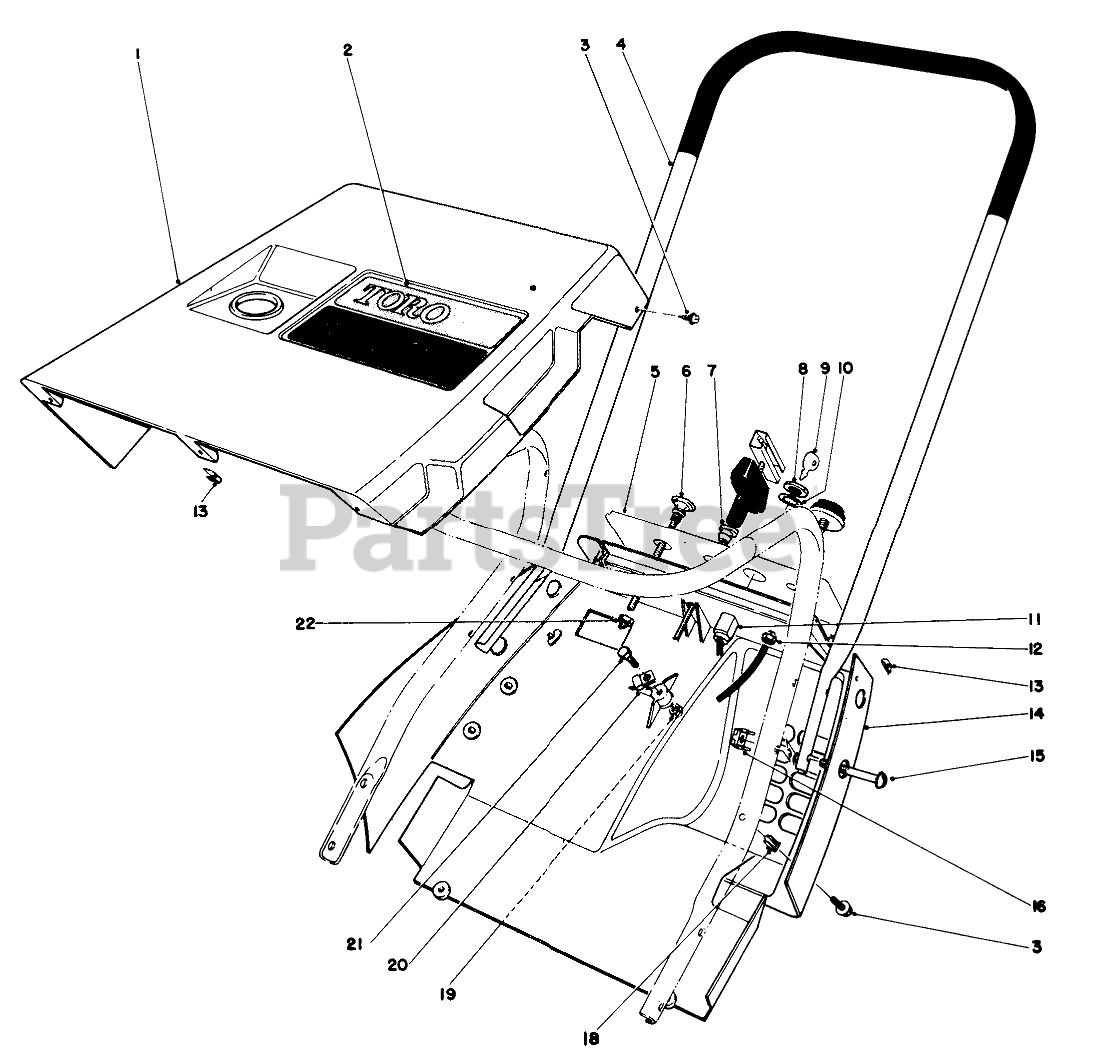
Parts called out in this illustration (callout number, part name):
1	Upper Shroud
2	Decal-Toro
3	SCREW-HWHTF
4	Upper Handle
5	Decal-Control Panel
6	Choke Cable
7	GUIDE-ROPE, STARTER
8	NUT-HH
9	Key
10	WASHER-TOOTH, INTERNAL
11	SWITCH-ON / OFF
12	NUT-KEPS
13	NUT-TYPE J
14	LOWER SHROUD
15	Sems Mach. Screw
16	TINNERMAN NUT
18	Push Nut
19	NUT-LOCK, NI
20	3/16 SUPPORT
21	SCREW-HWH
22	PAL NUT/CHOKE CNTRL
